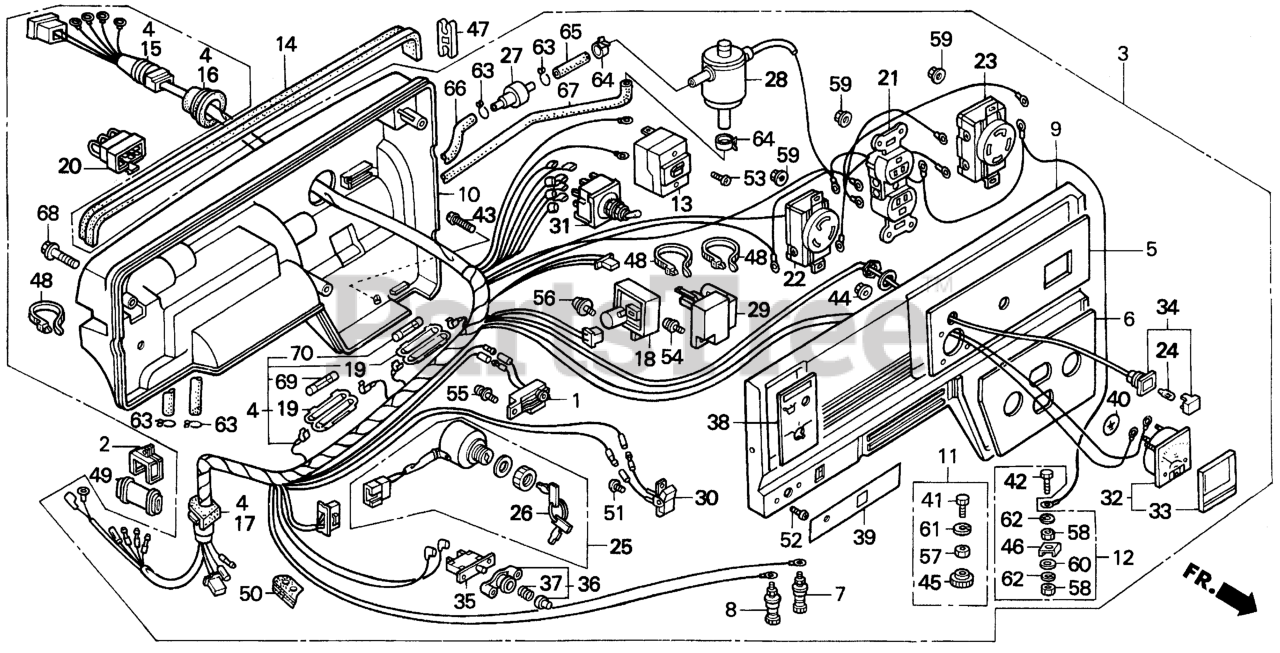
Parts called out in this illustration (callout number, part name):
1	ALERT UNIT, OIL (NOT AVAILABLE)
1	ALERT UNIT, OIL
2	CLIP, WIRE
3	BOX ASSY., CONTROL *R8* (EMS-A) (BRIGHT RED)
3	BOX ASSY., CONTROL *R8* (BRIGHT RED)
4	WIRE HARNESS ASSY. (EMS-A)
4	WIRE HARNESS ASSY. (EMS-A) (NOT AVAILABLE)
5	MARK, SWITCH PANEL (EMS-A)
6	MARK, A.C. OUT (EMS-A) (NOT AVAILABLE)
6	MARK, A.C. OUT (EMS-A)
7	TERMINAL, D.C. OUT (+)
8	TERMINAL, D.C. OUTPUT (-)
9	PANEL, CONTROL *R280* (POWER RED)
10	CASE, CONTROL *R8* (BRIGHT RED)
11	TERMINAL SET, GROUND
12	TERMINAL SET, GROUND
13	BREAKER, CIRCUIT (19A)
14	RUBBER, CONTROL
15	GROMMET, A.C. WIRE
16	GROMMET, MAIN WIRE
17	GROMMET, SWITCH WIRE
18	DIODE ASSY.
19	CASE, FUSE CONNECTOR (SUMITOMO)
20	CONNECTOR ASSY.
21	RECEPTACLE (20A/125V) (MATSUSHITA)
22	RECEPTACLE (30A/125V)
22	RECEPTACLE (3-PRONG) (30A/125V)
23	RECEPTACLE (4-PRONG) (30A/125-250V)
23	RECEPTACLE (30A/125-250V)
24	BULB, WEDGE BASE (12V/2W) Use from Frame SN 1001725.
25	SWITCH ASSY., COMBINATION
26	KEY
27	VALVE, DASHPOT CHECK
28	VALVE ASSY., SOLENOID
29	THROTTLE UNIT, AUTO (SAWAFUJI)
30	SWITCH, AUTO THROTTLE
31	SWITCH ASSY., VOLT CHANGE
32	METER ASSY., VOLT (300V)
33	LENS, METER
34	SOCKET ASSY., LAMP (GREEN) Use from Frame SN 1001725.
34	HOLDER, LAMP
35	PROTECTOR, CIRCUIT (D.C.)
36	LENS ASSY., PROTECTOR
37	SPRING, COIL
38	MARK, ENGINE SWITCH (EMS-A)
39	MARK, D.C. OUT (NOT AVAILABLE)
40	MARK, GROUND
41	BOLT, HEX. (6X22)
42	BOLT, HEX. (6X28)
43	SCREW, GLOVE BOX
44	NUT, FLANGE (3MM) Use from Frame SN 1001725.
45	NUT, SPECIAL (6MM)
46	RETAINER (6MM)
47	CLIP, TUBE
48	TIE, CABLE (NATURAL 225X5.0)
49	TUBE, CORD
50	GROMMET, TUBE
51	SCREW, PAN (3X6)
52	SCREW, PAN (3X12)
53	SCREW, PAN (4X6)
54	SCREW-WASHER (5X12)
55	SCREW-WASHER (4X10)
56	SCREW-WASHER (4X12) Use up to Engine SN 2056819.
57	NUT, HEX. (6MM)
58	NUT, HEX. (6MM)
59	NUT, FLANGE (4MM)
60	WASHER, PLAIN (6MM)
61	WASHER, SPRING (6MM)
62	WASHER, SPRING (6MM)
63	CLIP, TUBE (B7)
64	CLIP, TUBE (D8)
65	BULK HOSE, VACUUM (3.5X8000) (3.5X130)
66	BULK HOSE, VACUUM (3.5X8000) (3.5X130)
67	BULK HOSE, VACUUM (3.5X8000) (3.5X130)
68	BOLT, FLANGE (6X40)
69	FUSE B (5A)
70	FUSE B (10A)
